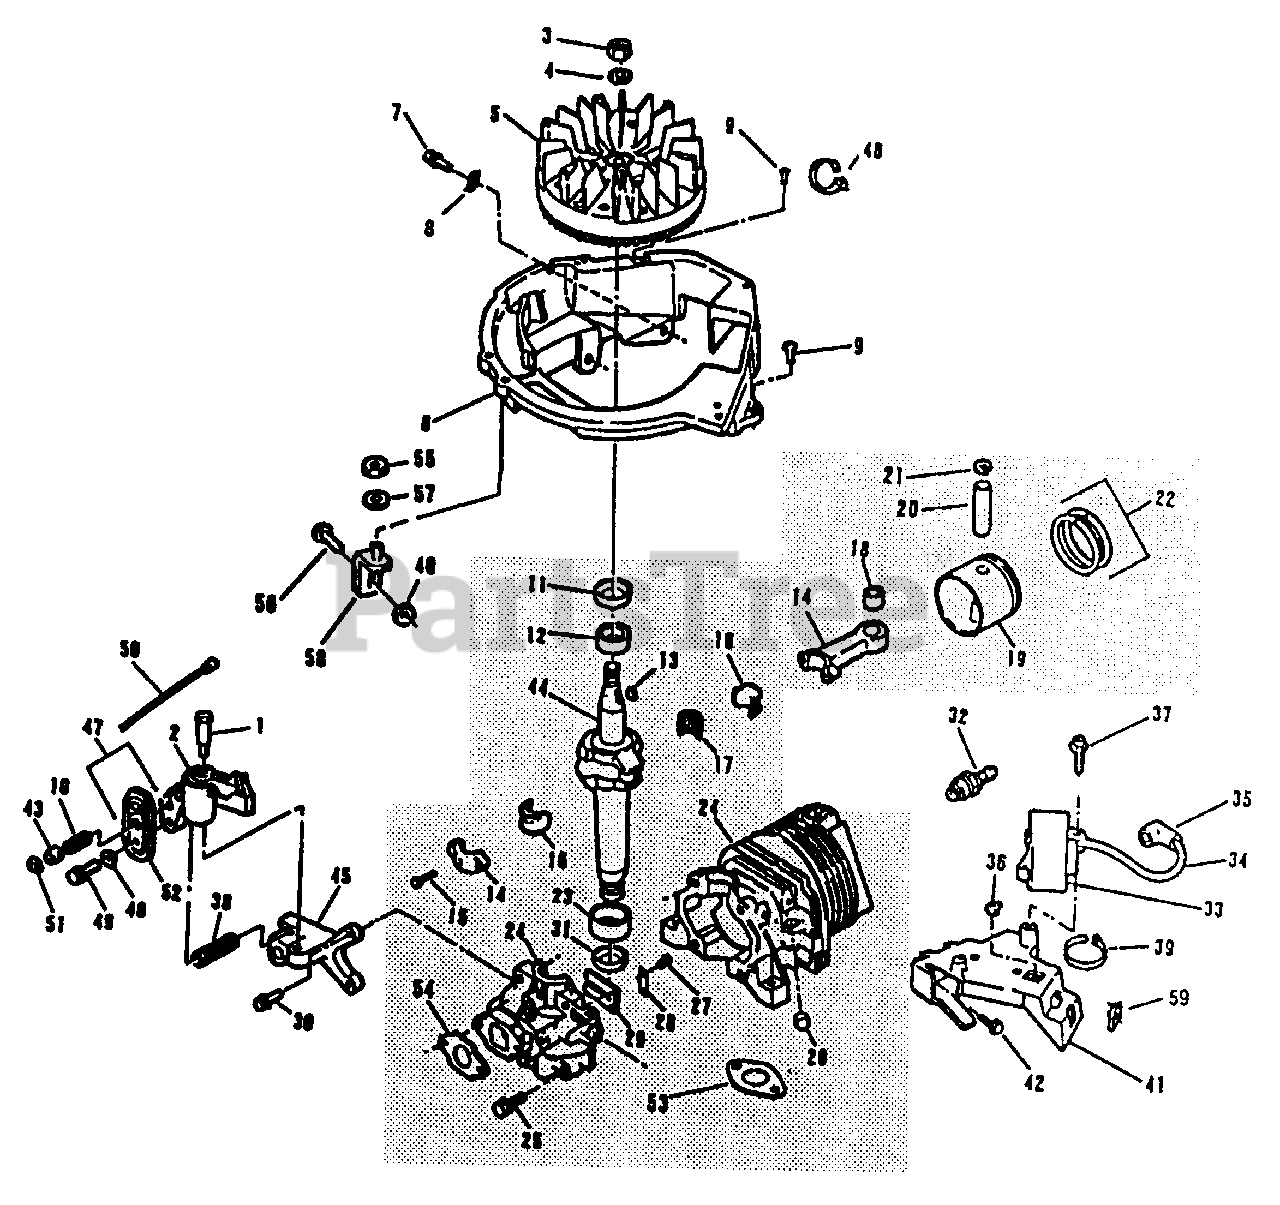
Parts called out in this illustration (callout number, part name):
1	Bolt-Shoulder
2	Brake Assembly
3	Nut-Flywheel
4	Lockwasher
5	Flywheel Assembly
6	Base-Shroud
7	Screw
8	Clip-"J"
9	Screw
10	Spring-Cable Return
11	Oil Seal-Upper
12	Bearing-Main-Upper
13	Key-Flywheel
14	Connecting Rod Assembly
15	Screw-Cap
16	Liner Split
17	Needle Bearing Set
18	Bearing Assembly
19	Piston and Ring Set
20	Wrist Pin
21	Retaining Ring
22	Ring Set
23	Bearing-Main-Lower
24	Cylinder and Crankcase Cover Asy.
25	Screw-Cover to Crankcase
26	Plug
27	Screw-Reed to C'case Cover
28	Plate-Reed Hold Down
29	Reed
30	Screw-Brake Mounting Bkt.
31	Oil Seal-Lower
32	Spark Plug
33	C.D. Ignition Module and Lead As
34	High Tension Lead & Cover Asy.
35	Spring Terminal
36	Grommet
37	Screw-C.D. Mounting
38	Spring-Brake
39	Tie Strap
40	Nut
41	Bracket-C.D. Mounting
42	Screw
43	Actuator-Brake Lever
44	Crankshaft
45	Bracket-Brake
46	Tie Strap
47	Switch Assembly
48	Washer
49	Screw
50	Lead Assembly
51	Retainer
52	Case Assembly-Only
53	Exhaust Gasket
54	Carburetor Gasket
55	Nut
56	Bolt
57	Washer
58	Brace Assembly
59	Speed Nut
